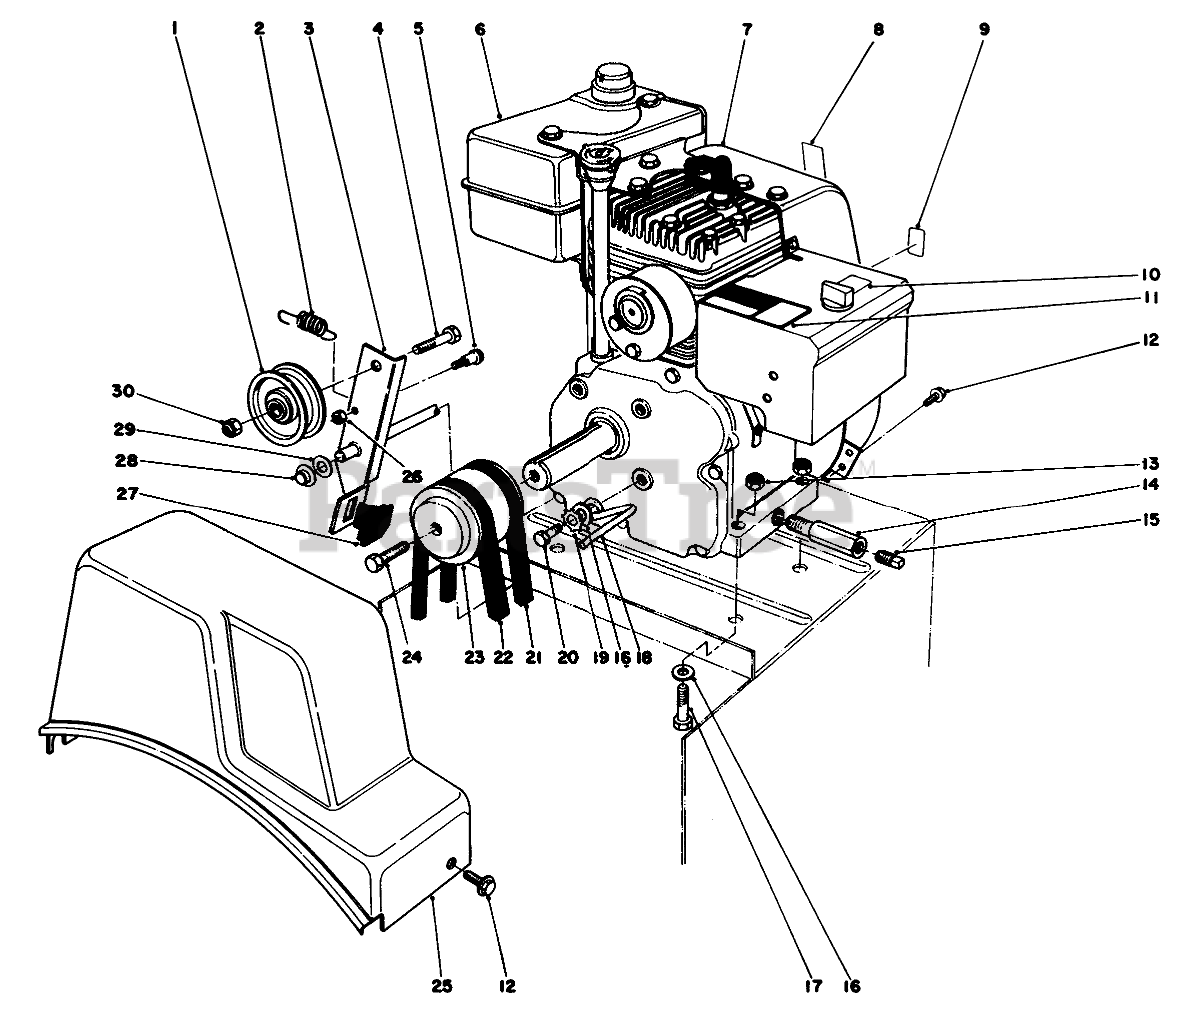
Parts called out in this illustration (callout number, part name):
1	PULLEY-IDLER
2	SPRING
3	Auger Clutch Rod Assembly (Incl. Ref. #27)
4	SCREW-HH
5	BOLT-SHOULDER
6	GAS TANK 2 QT W CAP
8	DECAL-PRIMER
9	THROTTLE DECAL, INT'L
10	CHOKE DECAL
11	Decal-Hot
12	Bolt 1/4-20
13	NUT-LOCK, NI
14	PIPE-NIPPLE
15	CAP-PIPE
16	WASHER-PLAIN
17	SCREW-HH
18	RETAINER-BELT
19	WASHER-LOCK
20	SCREW-HH
21	V BELT-3L, TRACTION
22	V-BELT (29.50 INCH)
23	PULLEY-ENGINE
24	SCREW-SPECIAL
25	COVER-BELT
26	NUT-LOCK, CONE
27	Brake Pad
28	RETAINER-PUSH ON
29	WASHER-FLAT
30	NUT-LOCK, CONE
